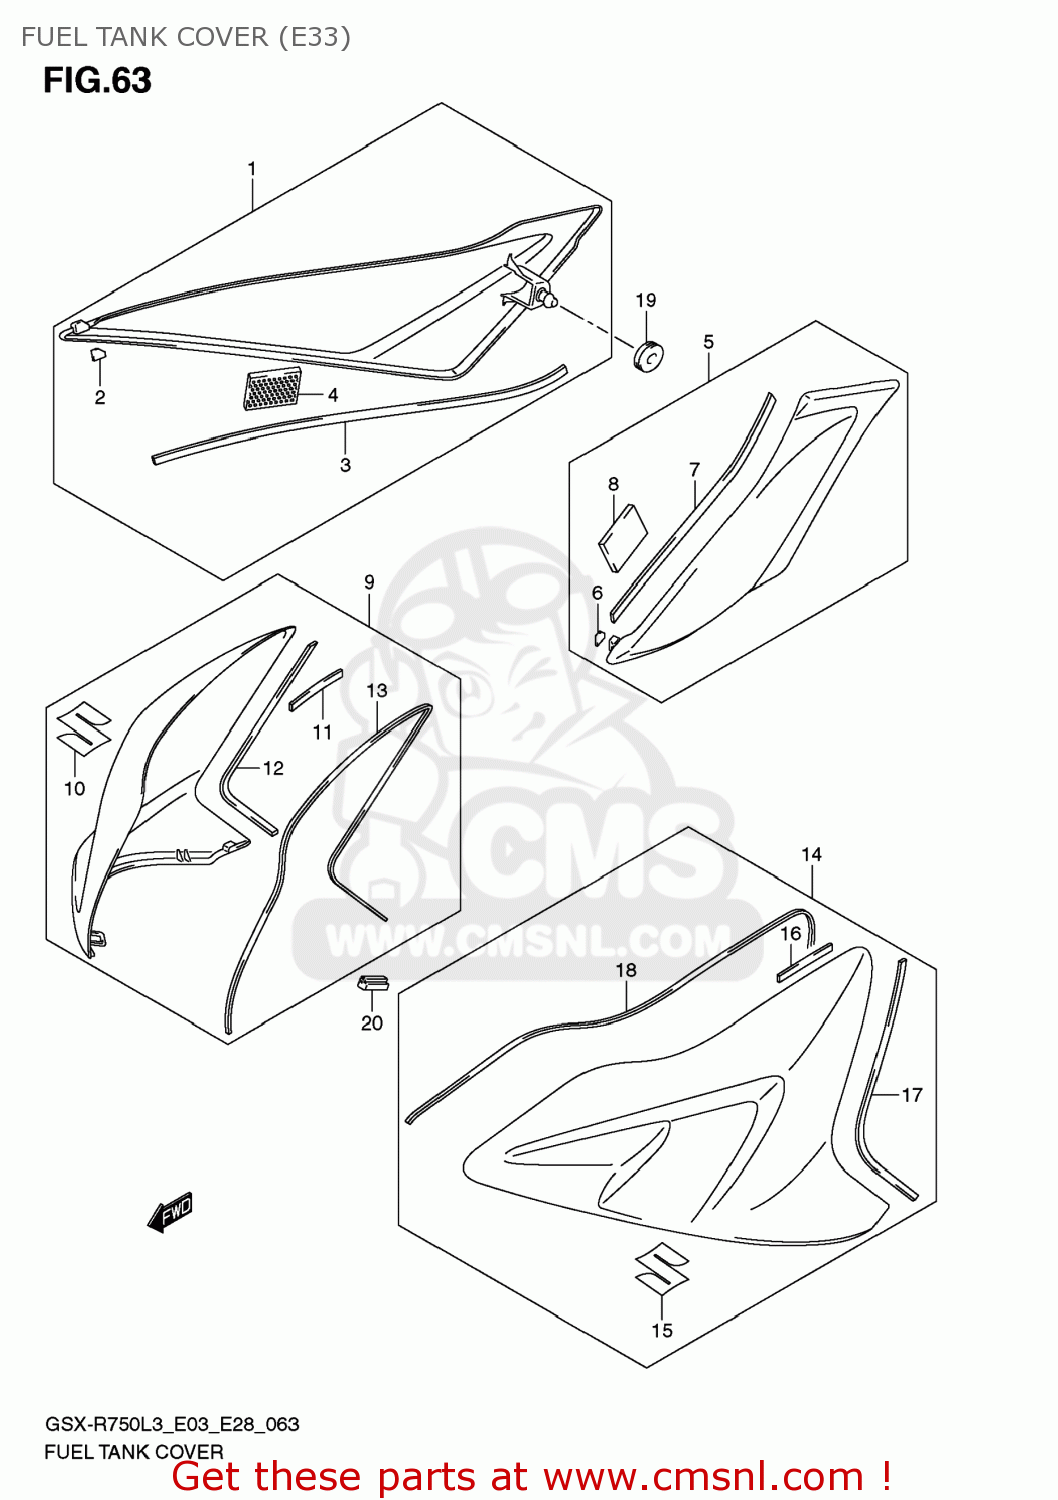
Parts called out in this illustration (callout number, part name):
1	COVER,FUEL TANK SIDE,R
2	CUSHION,FUEL TANK COVER
3	CUSHION,FUEL TANK SIDE COVER
4	FASTENER
5	COVER,FUEL TANK SIDE,L
6	CUSHION,FUEL TANK COVER
7	CUSHION,FUEL TANK SIDE COVER
8	FASTENER
9	COVER,FUEL TANK FR,R
10	EMBLEM,S
11	CUSHION,FUEL TANK COVER NO.1
12	CUSHION,FUEL TANK COVER,R NO.2
13	CUSHION,FUEL TANK COVER FR
14	COVER,FUEL TANK FR,R
15	EMBLEM,S
16	CUSHION,FUEL TANK COVER NO.1
17	CUSHION,FUEL TANK COVER,L NO.2
18	CUSHION,FUEL TANK COVER FR
19	CUSHION,FUEL TANK COVER SIDE
20	CUSHION,FUEL TANK COVER FR
